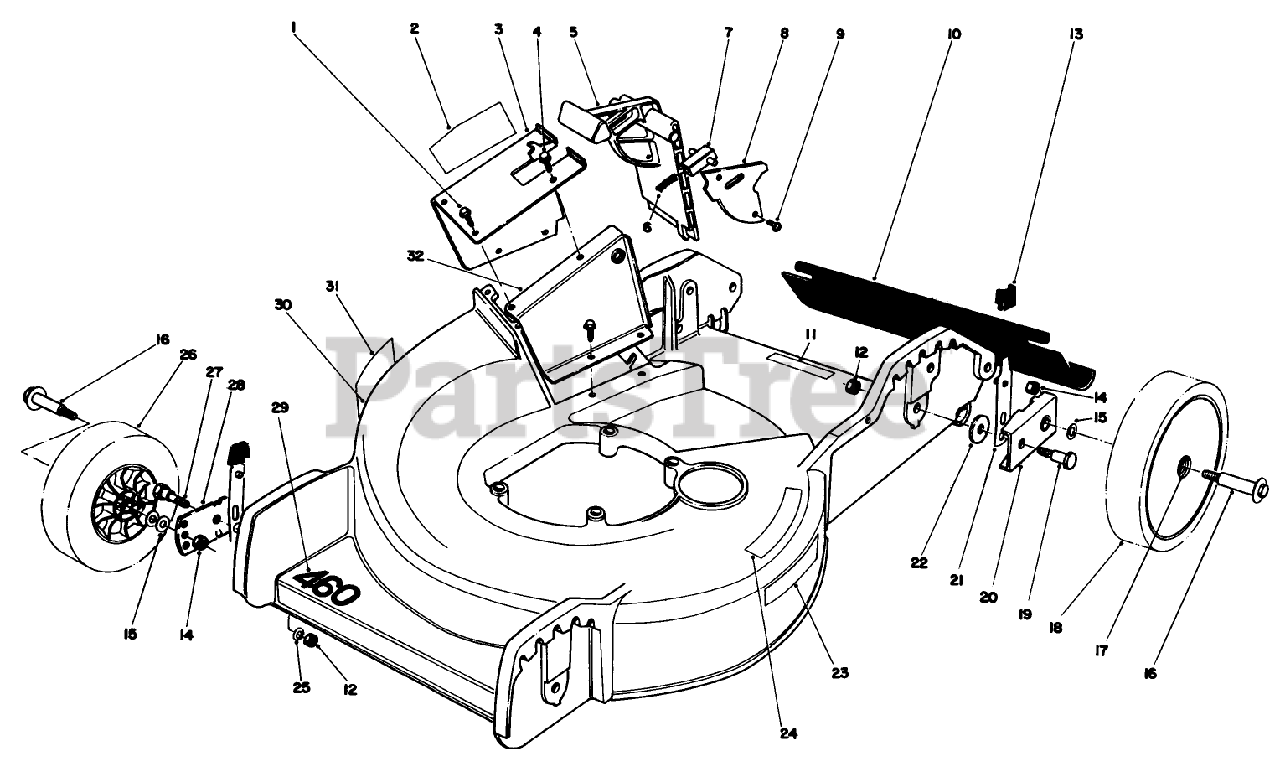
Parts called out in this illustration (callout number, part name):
1	SCREW
4	SCREW
6	SPRING-COMPRESSION, LATCH
10	SHIELD - TRAILING
12	NUT-LOCK, NI
13	KNOB-ARM
15	WASHER
16	BOLT-WHEEL
17	BUSHING
19	PIVOT SCREW
21	SPRING ARM ASM
22	PIVOT WASHER
24	STEP PAD DECAL
25	WASHER-BELLEVILLE
27	5/16-18 PIVOT SCREW
28	PIVOT ARM ASSY
